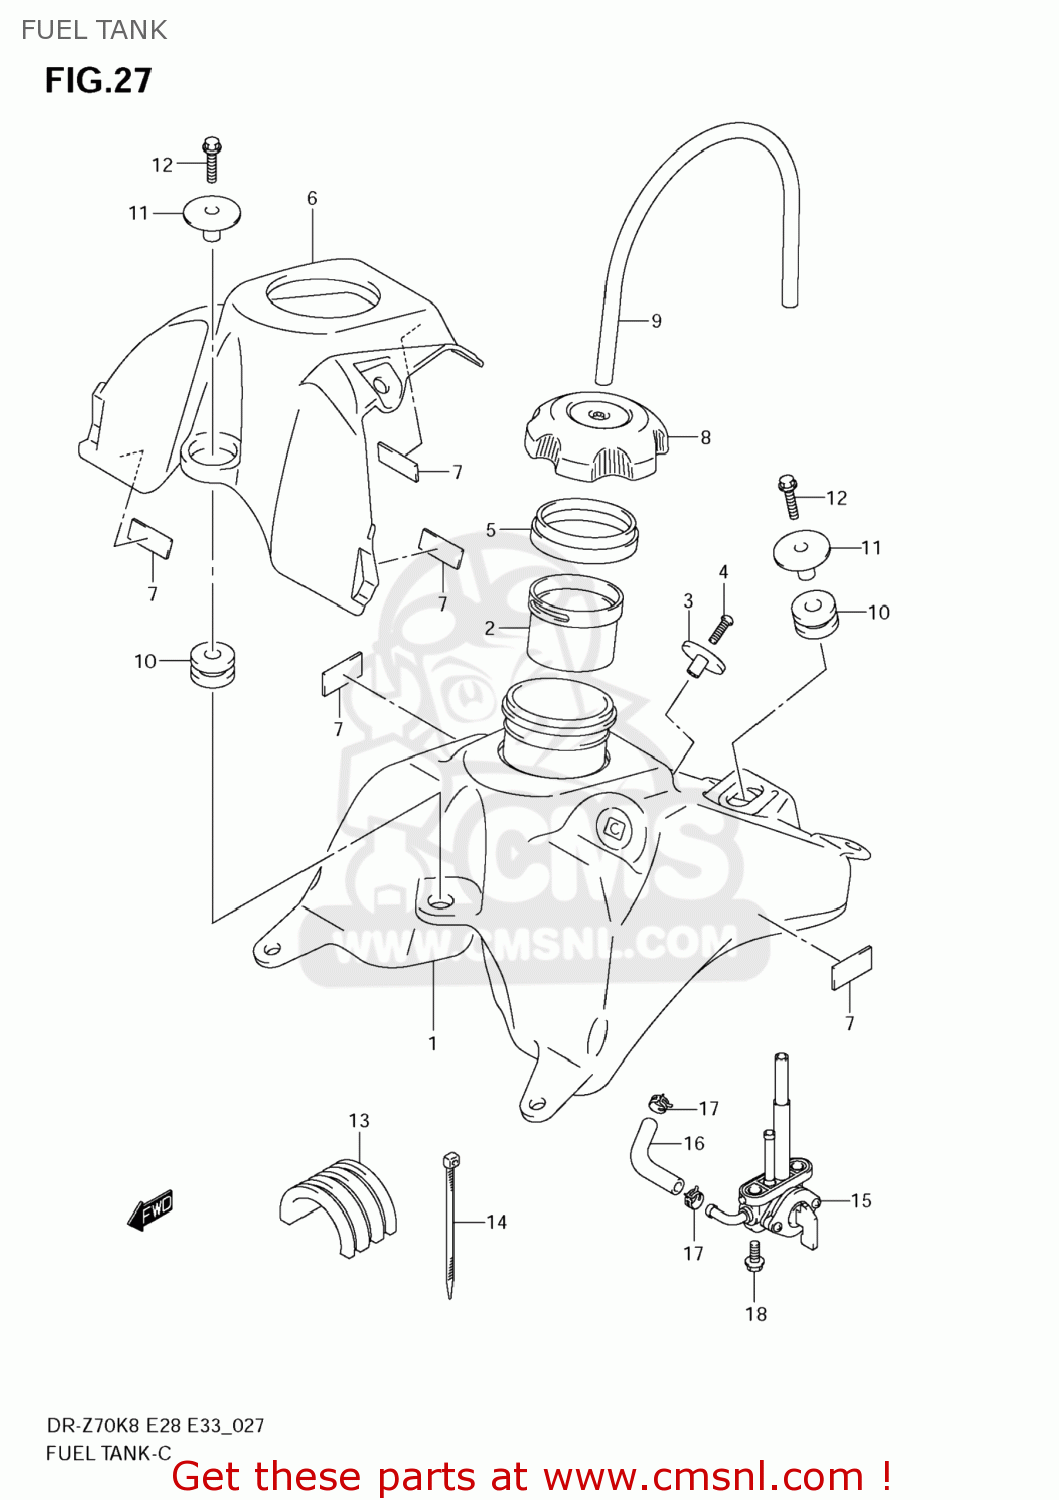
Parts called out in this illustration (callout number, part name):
1	TANK ASSY,FUEL
2	TUBE,FILLER INLET
3	HOOK,SEAT FR
4	BOLT(6X20)
5	RUBBER,FUEL TANK INLET
6	COVER,FUEL TANK UPR
7	CUSHION,FUEL TANK COVER
8	CAP ASSY,FUEL TANK FILLER
9	HOSE(5X8.2X600)
10	CUSHION,FUEL TANK RR
11	WASHER,FUEL TANK
12	BOLT
13	CUSHION,FUEL TANK
14	CLAMP(L:300)
15	COCK ASSY,FUEL
16	HOSE,FUEL
17	CLIP
18	BOLT
